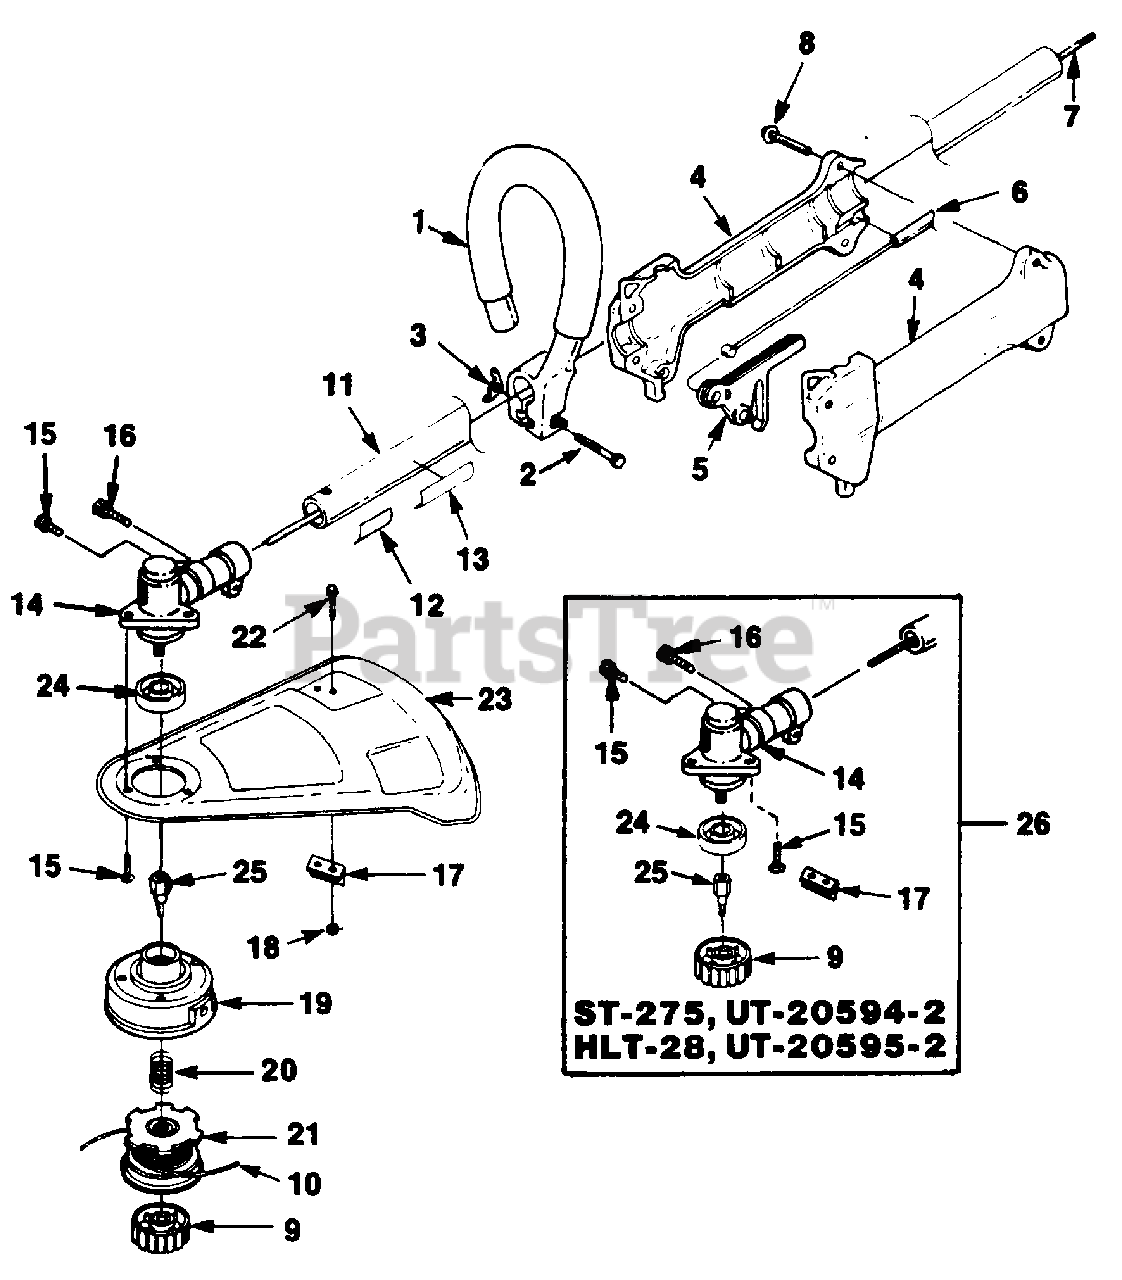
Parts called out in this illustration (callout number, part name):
1	HANDLE- Front
2	SCREW (1/4-20 x 2")
3	NUT- Wing
4	HANDLE GRIP ASSEMBLY
5	TRIGGER
6	CABLE- Throttle
7	SHAFT- Flexible
8	SCREW- Plastite (#8 x 3/4")
9	RETAINER- Spool
10	LINE- Replacement (.080 Dia.) (100 Ft.) (ST-275)
11	HOUSING- Drive shaft (ST-275- UT20594-1)
12	DECAL- Warning
13	DECAL- Starting Instructions
14	GEAR HEAD
15	SCREW- (10-24 x 3/8")
16	SCREW- (1/4-20 x 7/8")
17	BLADE- Cut-off (HLT-28)
18	NUT (10-24)
19	HOUSING & EYELET (Dual Line)
20	SPRING- Compression
21	SPOOL & STRING (Dual Line) (ST-275)
22	SCREW (10-24 x 3/8")
23	DEFLECTOR- Grass
24	WASHER- Flange (ST-275- UT20594-1, HLT-28 UT20595-A)
25	ADAPTOR- Shaft (ST-275- UT20594-1) (HLT-28- UT20595-A)
26	GEAR BOX KIT (ST-275- UT20594-2, HLT-28- UT-20595-2)
